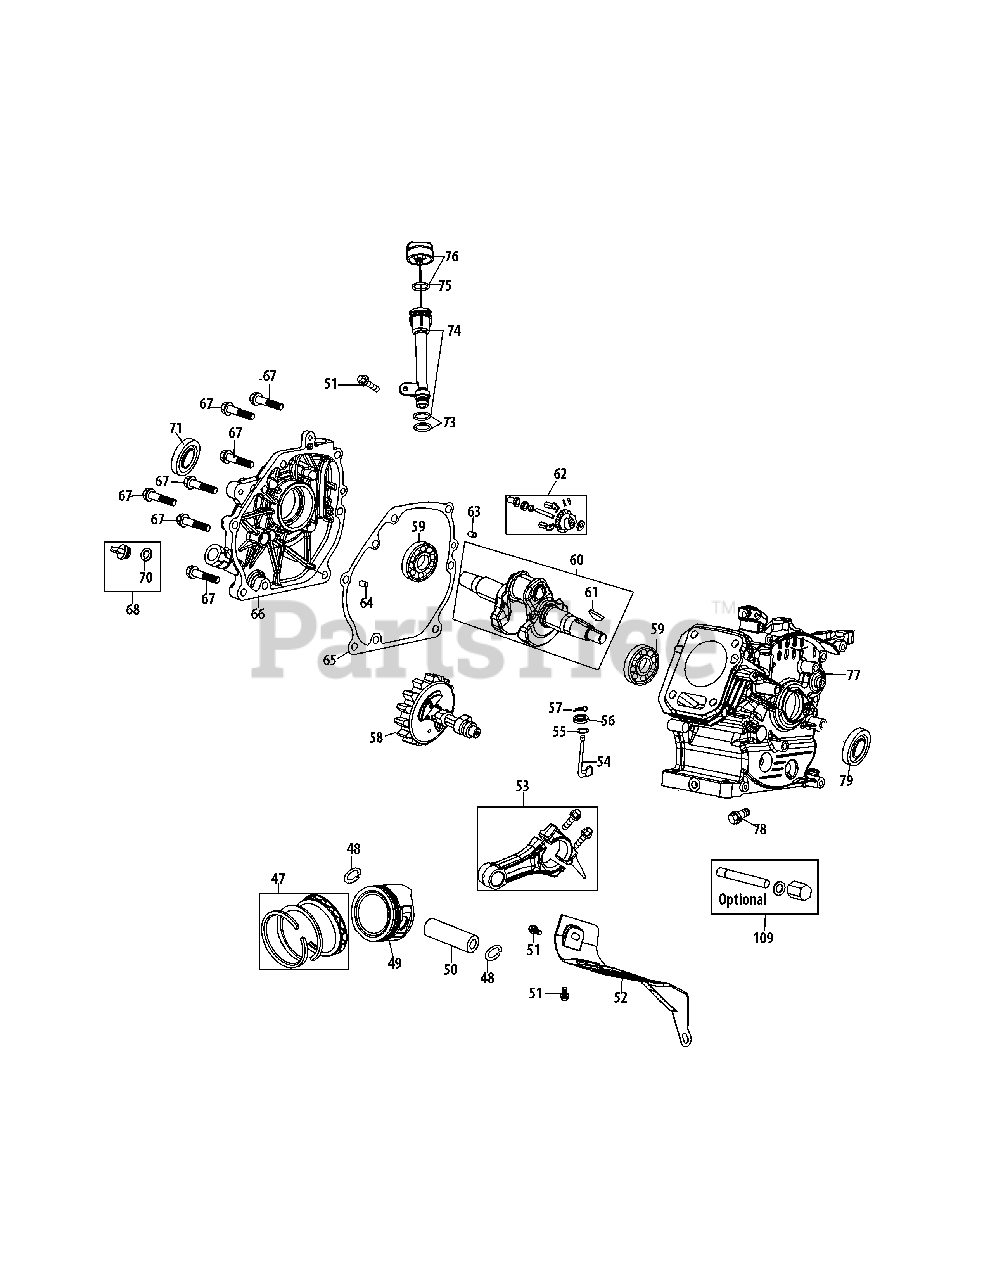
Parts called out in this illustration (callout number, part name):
47	Piston Ring Set
48	Piston Pin Snap Ring
50	Piston Pin
51	Bolt M6×12
52	Air Shield
53	Connecting Rod Assembly
54	Governor Arm Shaft
55	Washer 5.2×1.9
56	Governor Seal
57	Cotter Pin
58	Camshaft Assy.
59	Radial Ball Bearing, 6205
60	Crankshaft Kit
61	Woodruff Key
62	Governor Gear/Shaft Assembly
63	Dowel Pin 7×14
64	Dowel Pin 9×14
65	Crankcase Cover Gasket
66	Cover Comp, Left Crankcase
67	Bolt M8×32
68	Oil Fill Plug Assembly
70	O-Ring 15.8×2.5
71	Oil Seal, 25×41.25×6
73	Oil Fill Tube O-Ring
74	Oil Fill Tube Assembly
75	Dipstick O-Ring
76	Dipstick Assembly
77	Crankcase Kit
78	Oil Drain Plug
79	Oil Seal 25×41.25×6
109	Oil Drain Tube Kit (Optional)
